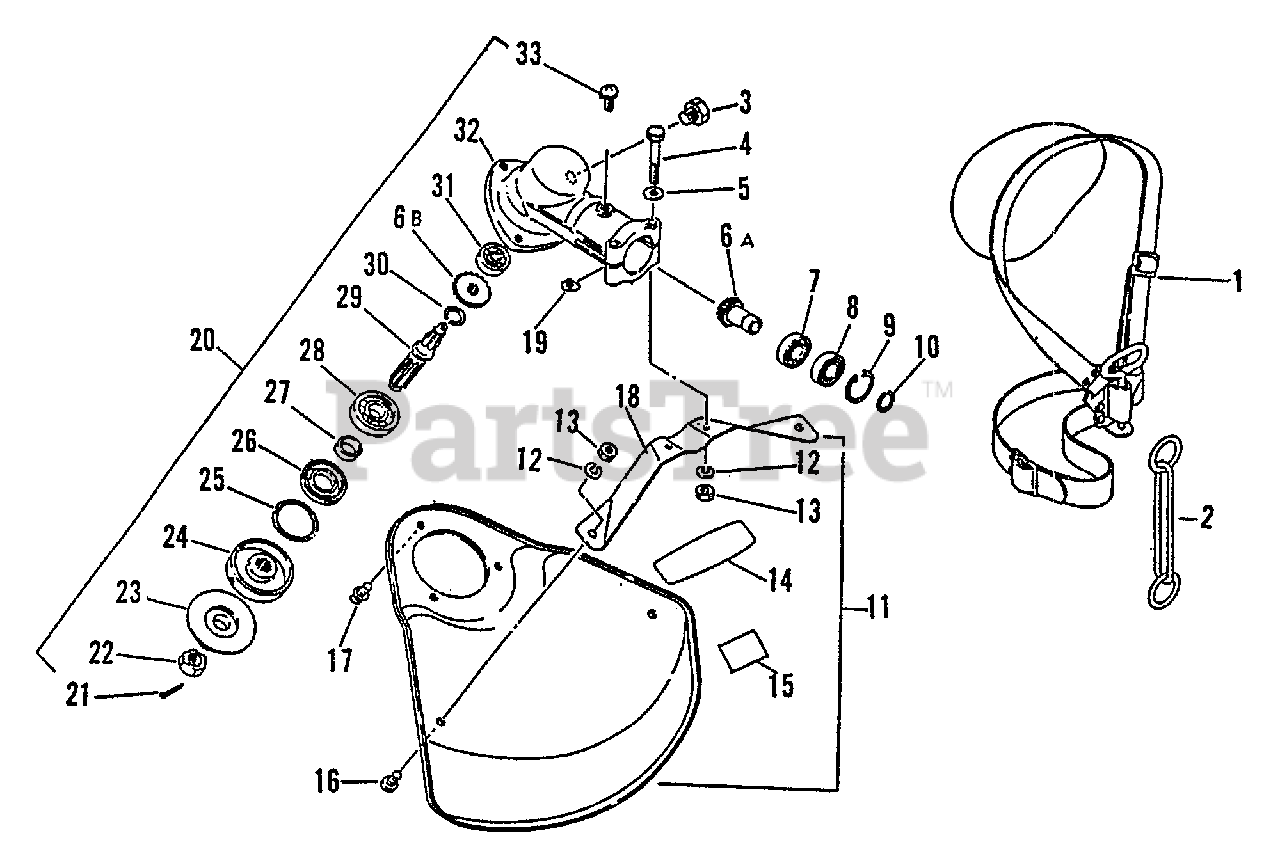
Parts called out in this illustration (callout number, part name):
1	SHOULDER STRAP ASSY
2	HOOK
3	BOLT 8×8 SP
4	BOLT 5×35 SP
5	WASHER, FLAT 5.5×10×0.8
6	GEAR SET
7	BEARING, BALL 6900
8	BEARING, BALL 6900Z
9	RING, SNAP Ø22
10	RING, SNAP Ø12
11	SHIELD ASSY
12	WASHER, SPRING 5
13	NUT M5
14	LABEL
15	LABEL - CAUTION
16	SCREW 5×8
17	SCREW 5×10
18	BRACKET, SHIELD MOUNTING
20	GEAR CASE ASSY
21	PIN, COTTER 2×22
23	PLATE, ADAPTOR - LOWER
24	PLATE, ADAPTER - UPPER
25	RING, SNAP Ø32
26	SEAL, OIL 22
27	SPACER 11.8×15×9
28	BEARING, BALL - 6201 C3
29	SHAFT, GEAR
30	RING, SNAP Ø10
31	BEARING, BALL 609
32	HOUSING, GEAR CASE
33	SCREW 5×10
